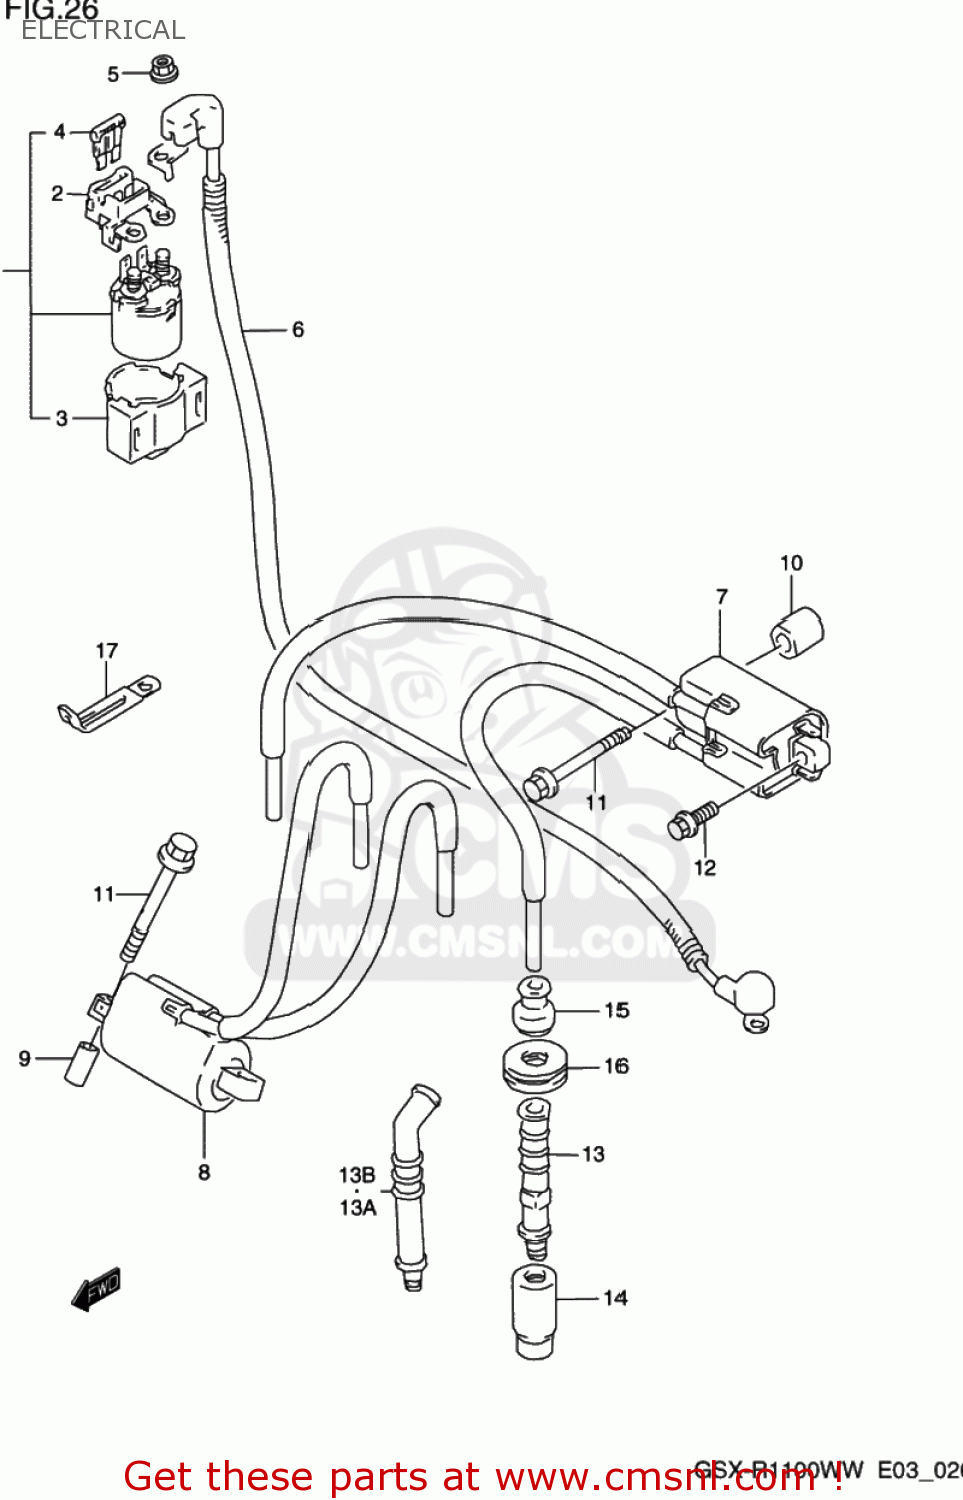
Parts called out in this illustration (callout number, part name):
1	RELAY ASSY,STARTING MOTOR
2	TERMINAL,RELAY
3	BRACKET,STARTING MOTOR RELAY
4	FUSE(30A)
5	NUT
6	WIRE,STARTER MOTOR
7	COIL ASSY,IGNITION
8	COIL ASSY,IGNITION
9	SPACER
10	SPACER,IGNITION COIL 1
11	BOLT
12	BOLT
13	CAP,SPARK PLUG
13A	CAP,SPARK PLUG
13B	CAP ASSY,SPARK PLUG
14	SEAL,SPARK PLUG
15	SEAL,HIGH TENSION CORD
16	COVER,SPARK PLUG CAP
17	CLAMP
